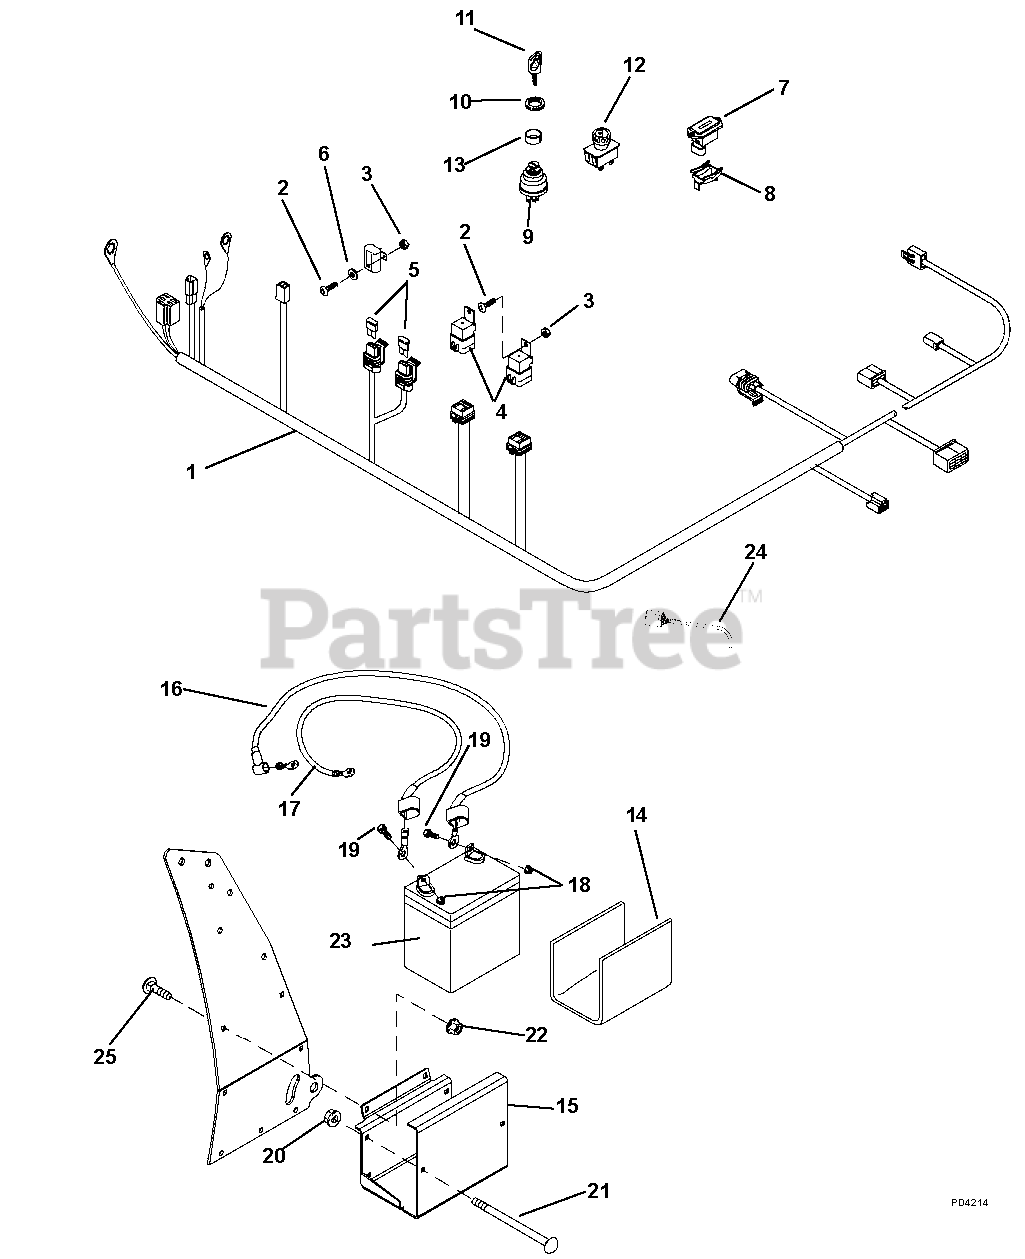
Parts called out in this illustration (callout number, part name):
1	Wiring Harness
2	Bolt, Hex M5 .8 x 16
3	Locknut, ISO7040-5-9-ZN
4	Relay, Sealed with Bracket
5	Fuse, 20 Amp Blade
6	Washer, Flat Steel .219 x .50 x .049
7	Meter, Hour - LCD
8	Clip, ZTrak Hour Meter
9	Switch, Ignition Key
10	Nut, Knurled
11	Ignition Key
12	Switch, PTO
13	Spacer, 1.00 x .095W x. 392
14	Strip, Rubber
15	Tray, Battery
16	Cable, Battery Starter 48"
17	Cable, Battery Ground 25"
18	Nut, Locking, Flange .25-20
19	Bolt, Hex .25-20 x .75 Grade 5
20	Nut, Locking, Nylon, Flange .31-18
21	Bolt, Round Head Square Neck .31-18 x 6.00 G5
22	Nut, Lock, Flange M8-1.25
24	Adapter, Pin Harness
25	Bolt, Round Head Square Neck M8-1.25 x 20
